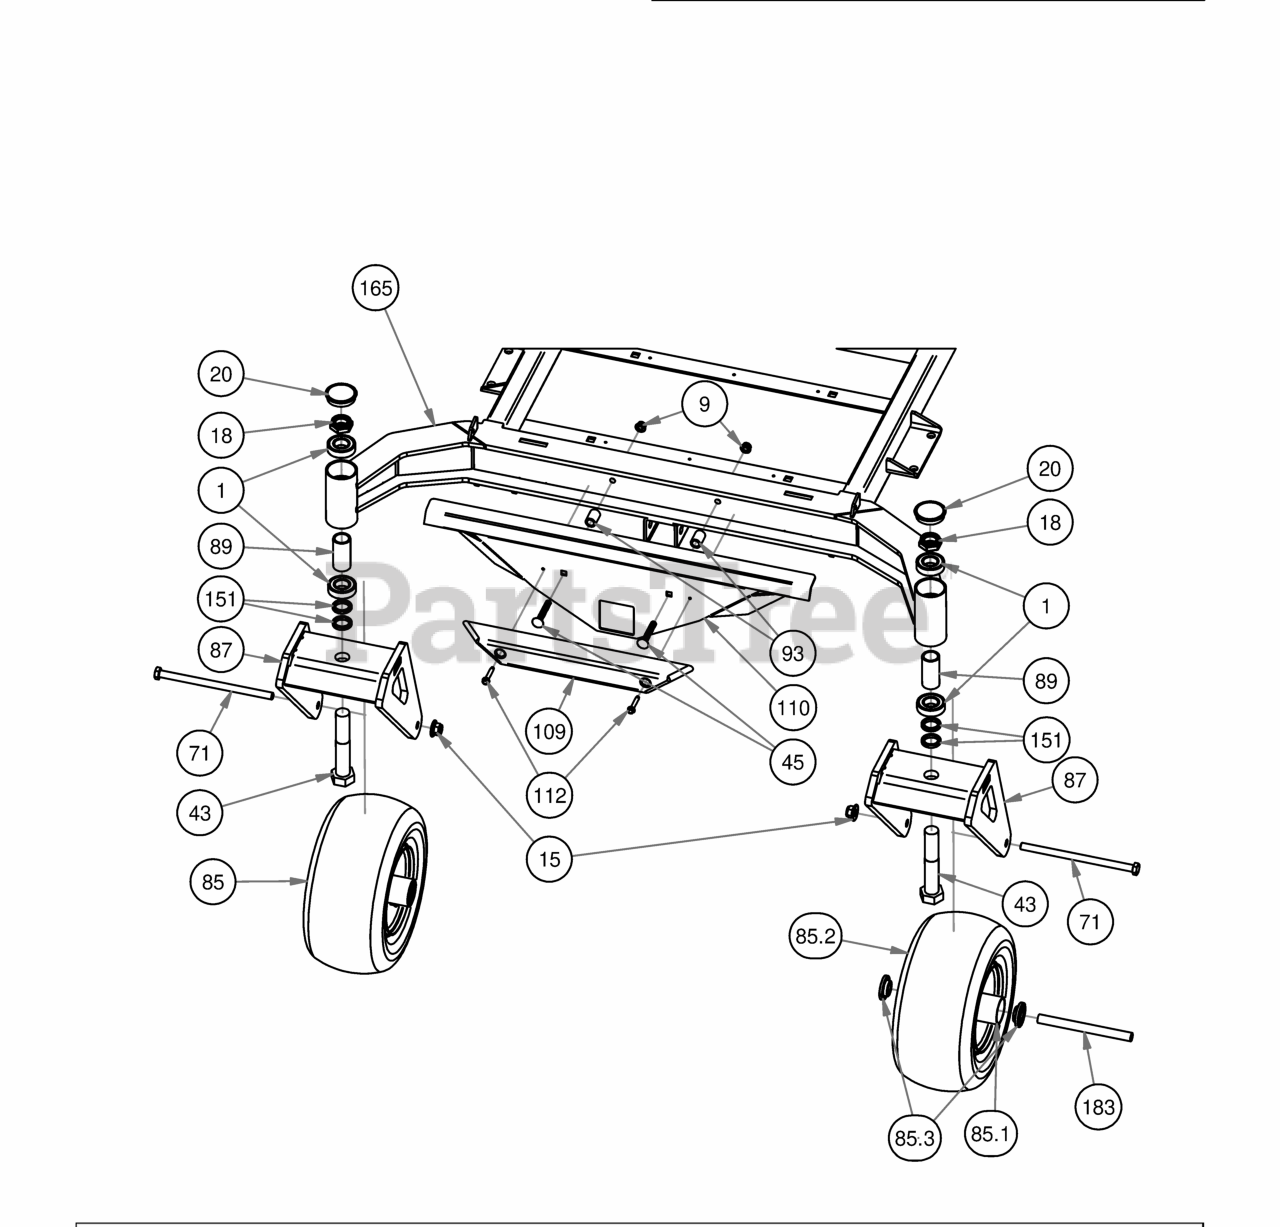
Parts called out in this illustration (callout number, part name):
1	1641 BEARING W/2 CONTACT RUBBER SEALS
9	3/8" Nylock Flange Nut
15	1/2-13 Nylon Flange Nut
18	1" Fine Thread 1/2 Nylock Nut
20	2017 Bearing Cover
43	1-14 x 5.5 Hex Bolt Grade 8 Zinc Yellow
45	3/8" x 2 1/2" Carriage Bolt
71	1/2" x 9" GR 5 Hex Bolt
85	Tire and black wheel assembly
85.1	Black Front Tire Rim
85.2	13 x 6.50 - 6 Tire
85.3	1-3/4" Bearing-Large Bore Front Rim
87	2019 Rebel Front Fork - Weldment
89	2016 Front Bearing Spacer
109	2017 XP Bumper
110	2019 Outlaw Rigid Front Bumper Plate
112	1/4" x 1 1/2" Self Tapping Screw
151	Spacer, 1x1.375x.25
165	2019 Rigid Frame
183	Front Wheel Spanner
